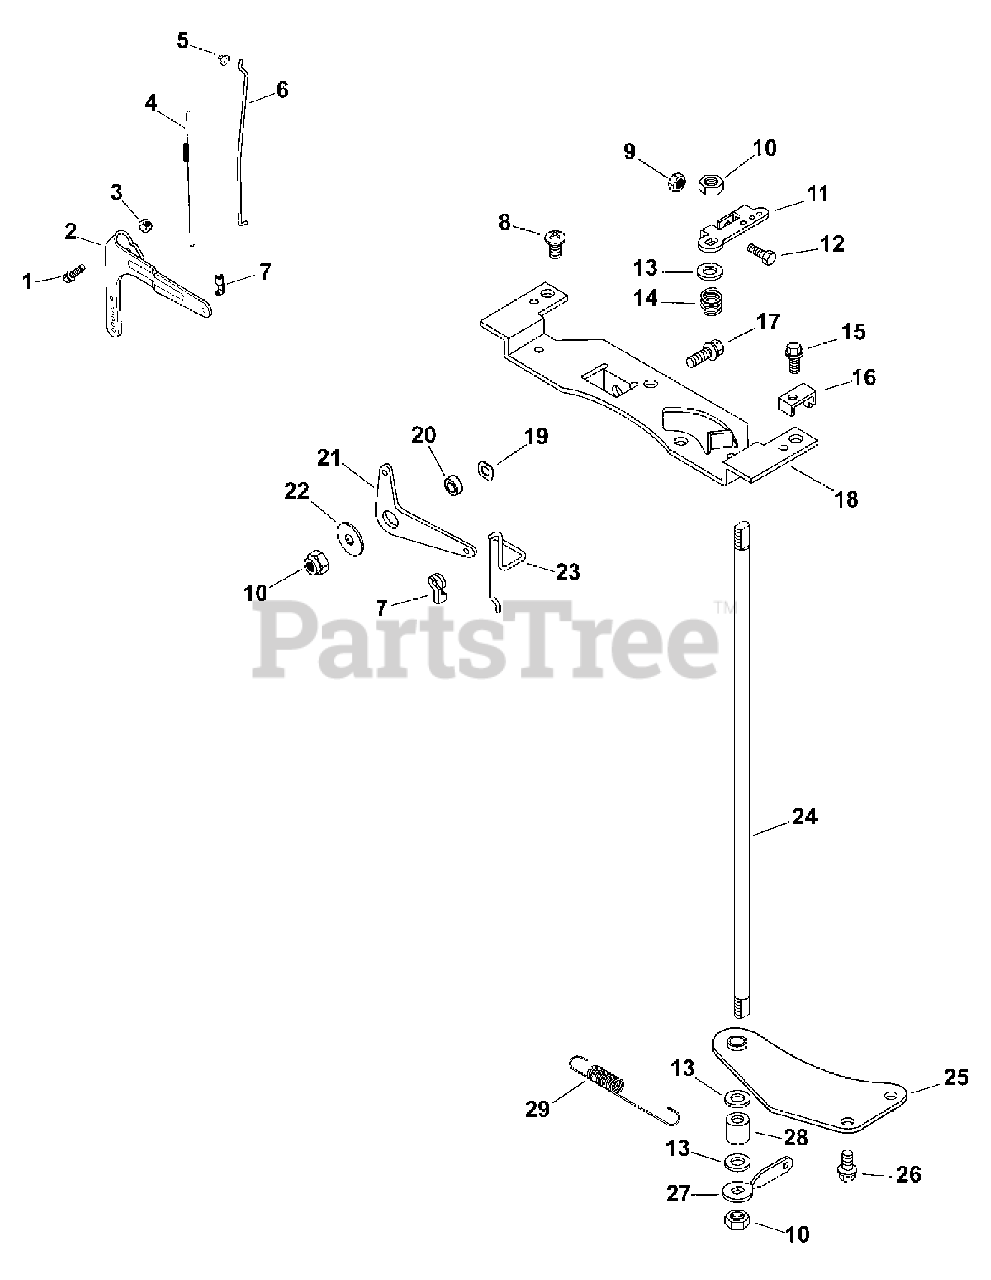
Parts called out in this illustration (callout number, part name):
1	BOLT, RD HD SQ NECK M6X1.0X25
2	LEVER, GOVERNOR-USE 24 090 57-S
3	NUT, FLG M6X1.0
4	SPRING, LINKAGE
5	BUSHING, LINKAGE RETAINING
6	LINKAGE, THROTTLE
7	BUSHING, THROTTLE LINKAGE
8	SCREW, PHL HD 11-16X3/4"
9	NUT, M4X0.7
10	NUT, LOCK M6X1.0
11	LEVER, THROTTLE CONTROL
12	SCREW, CAP M4X.7X30
13	WASHER, FLAT 1/4"
14	SPRING, THROTTLE SHAFT
15	SCREW,FLG THD FRM M5X0.8X16-(#25086398S)
16	CLAMP, CABLE
17	SCREW, FLG M6X1.0X16
18	BRACKET, CONTROL-USE 24 126 219-S
19	WASHER, SPRING 3/8"
21	LEVER, CHOKE
22	WASHER, FLAT 1/4"
23	LINKAGE, CHOKE
24	SHAFT, THROTTLE
25	BRACKET, THROTTLE SHAFT-USE 24 126 162-S
26	SCREW,FLG THD FRM M6X1.0X16-(#25086397S)
27	LEVER, THROTTLE CONTROL
29	SPRING, GOVERNOR (BLUE)
